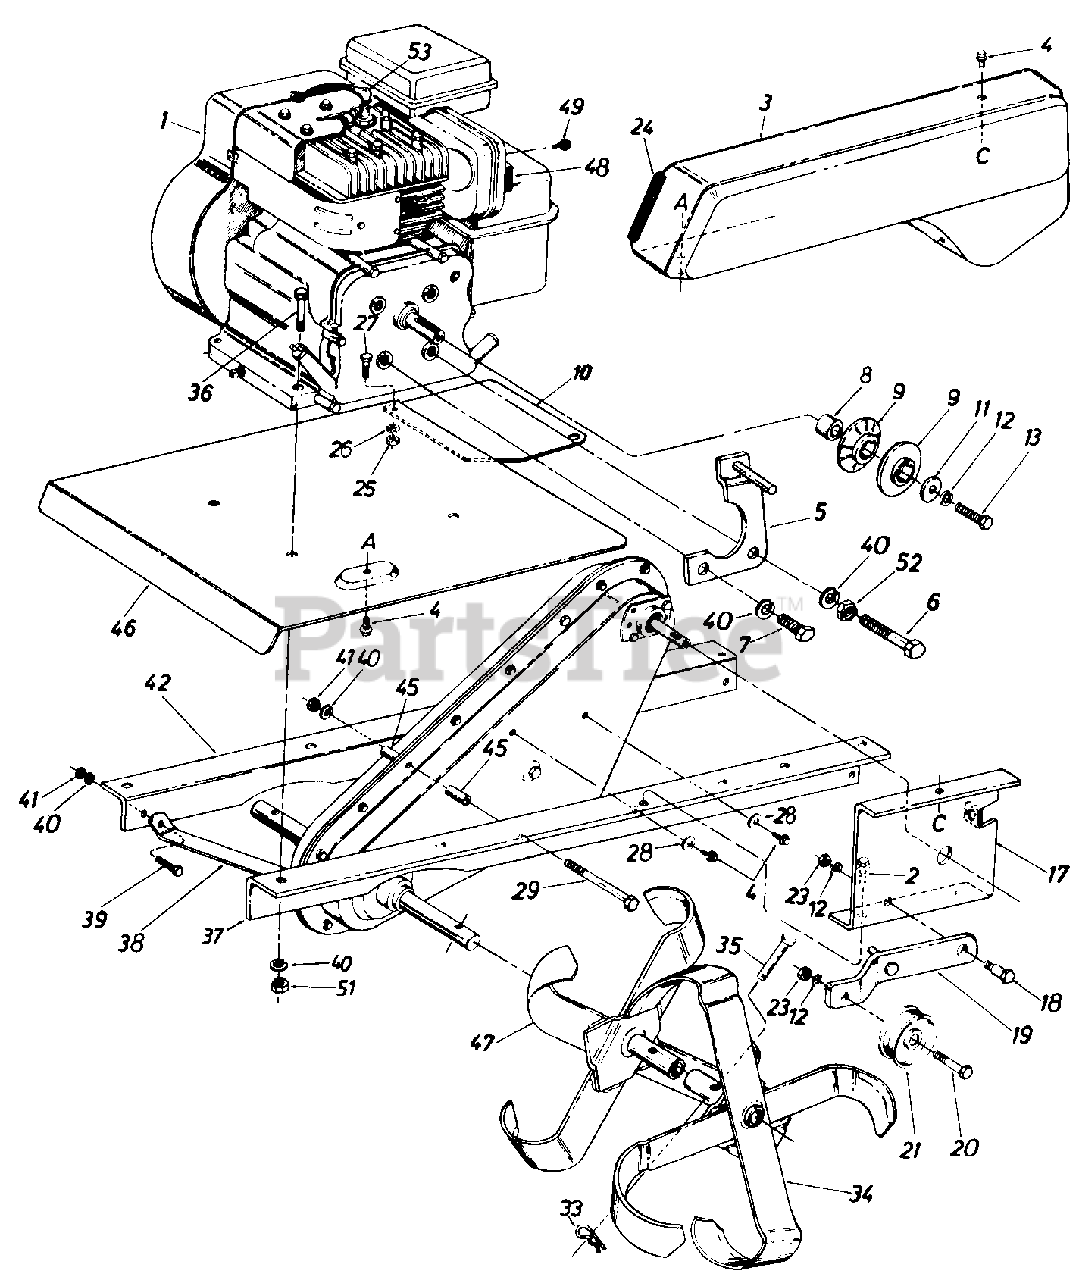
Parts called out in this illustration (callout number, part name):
1	Engine
2	Hex Self-Tap Scr. 5/16-24 X .5"
3	Belt Cover
4	Hex Self-Tap Scr. 1/4-20 X .5"
5	Belt Keeper Brkt. Ass'y.
6	Hex Bolt 5/16-24 X 2.25" Lg. (Gr. 5)
7	Hex Bolt 5/16-24 x .62" Lg. (Gr. 5)
10	Tine Shield Extension
11	Fl-Wash. 3/8" l.D. x 1.25"
12	L-Wash. 3/8" l.D.
13	Hex Bolt 3/8-24 x 1.00" Lg.
17	483Idler Mounting Brkt.
18	Shld. Bolt
19	Idler Bracket Ass'y.
20	Hex Bolt 3/8-16 x 1.5" Lg.
21	Idler Pulley
23	Hex Jam Nut 3/8-16 Thd.
24	Trim Strip-3"
25	Hex Nut 1/4-20 Thd.
26	L-Wash. 1/4" I.D.
27	Hex Bolt 1/4-20 x .62 Lg t
28	Bell-Wash. .26 I.D. x .75 O.D.
29	Hex Bolt 5/16-18 x 3" Lg.
33	Hairpin Cotter
34	See Tine Chart
35	Clevis Pin
36	Hex Bolt 5/16-18 x 1.5" Lg.
37	483Frame Rail-L.H.
38	Front Brace Brkt.
39	Hex Bolt 5/16-18 x .75" Lg.
40	L-Wash. 5/16" l.D.
41	Hex Cent. L-Nut 5/16-18 Thd.
42	483Frame Rail-R.H.
47	See Tine Chart
49	Hex Self-Tap Scr. #8-32 x .38"
51	Hex Nut 5/16-18 Thd.
52	Hex Nut 5/16-24 Thd.
53	Spark Plug Boot
